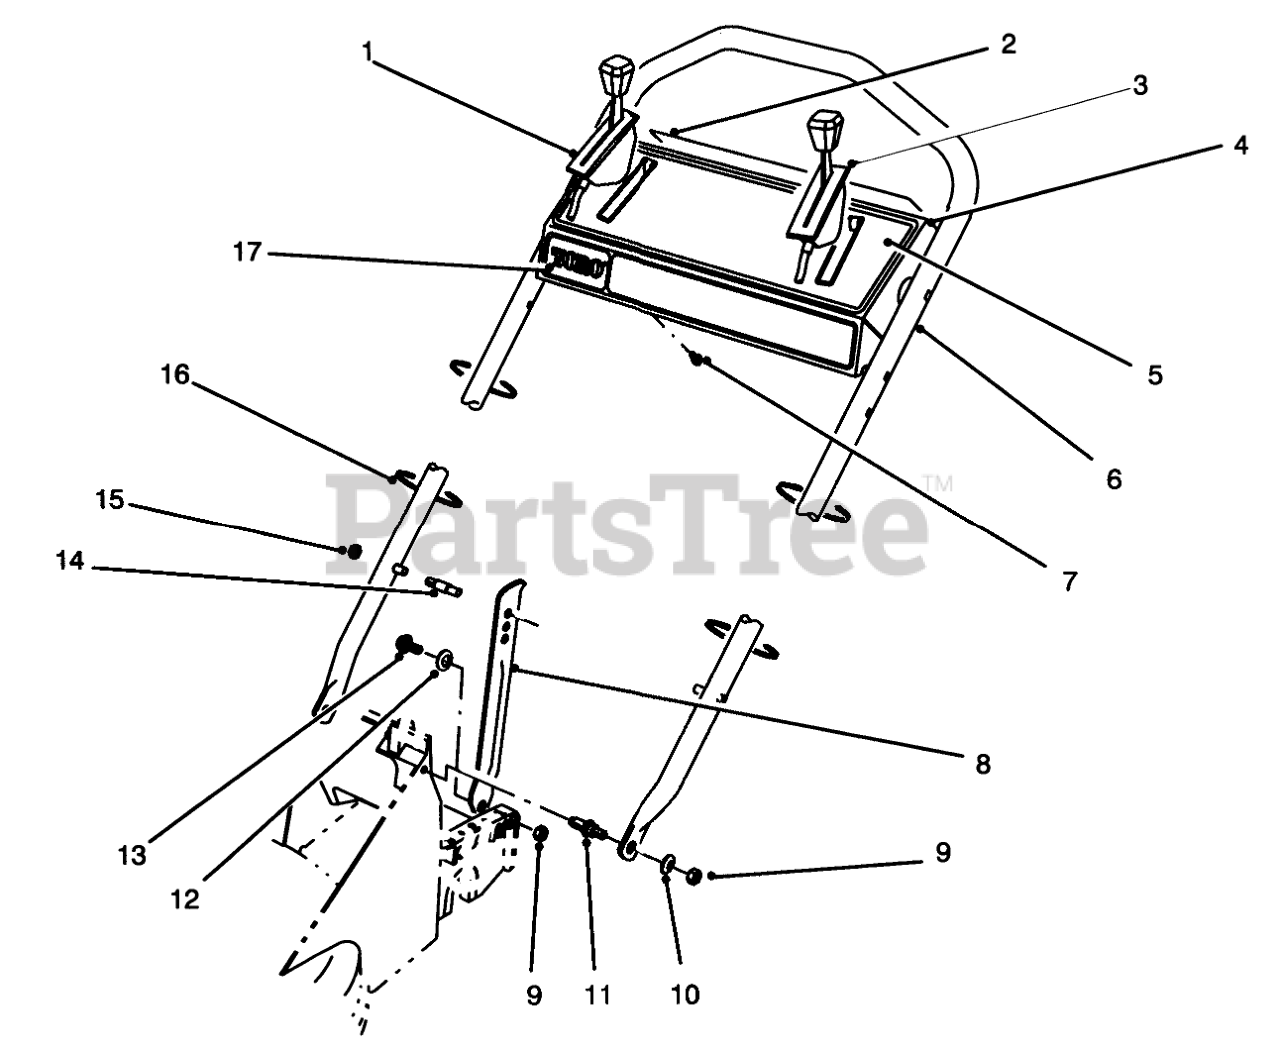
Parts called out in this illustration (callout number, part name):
1	GROUND SPEED CONTROL
2	DECAL - PANEL, REAR
3	THROTTLE CONTROL
4	Control Panel Assembly (Incl. Ref. #2 & 5)
5	DECAL - INSTRUCTION
6	UPPER HANDLE, PVC DIP
7	SCREW-HWHTF
8	HANDLE LATCH
9	NUT-LOCK, NI
10	WASHER-PLAIN
11	SCREW - SHOULDER STUD
12	NYLON WASHER
13	SCREW-SHOULDER
14	HANDLE PIN
15	NUT-LOCK, NI
16	TIE-CABLE
17	DECAL - TORO PANEL
